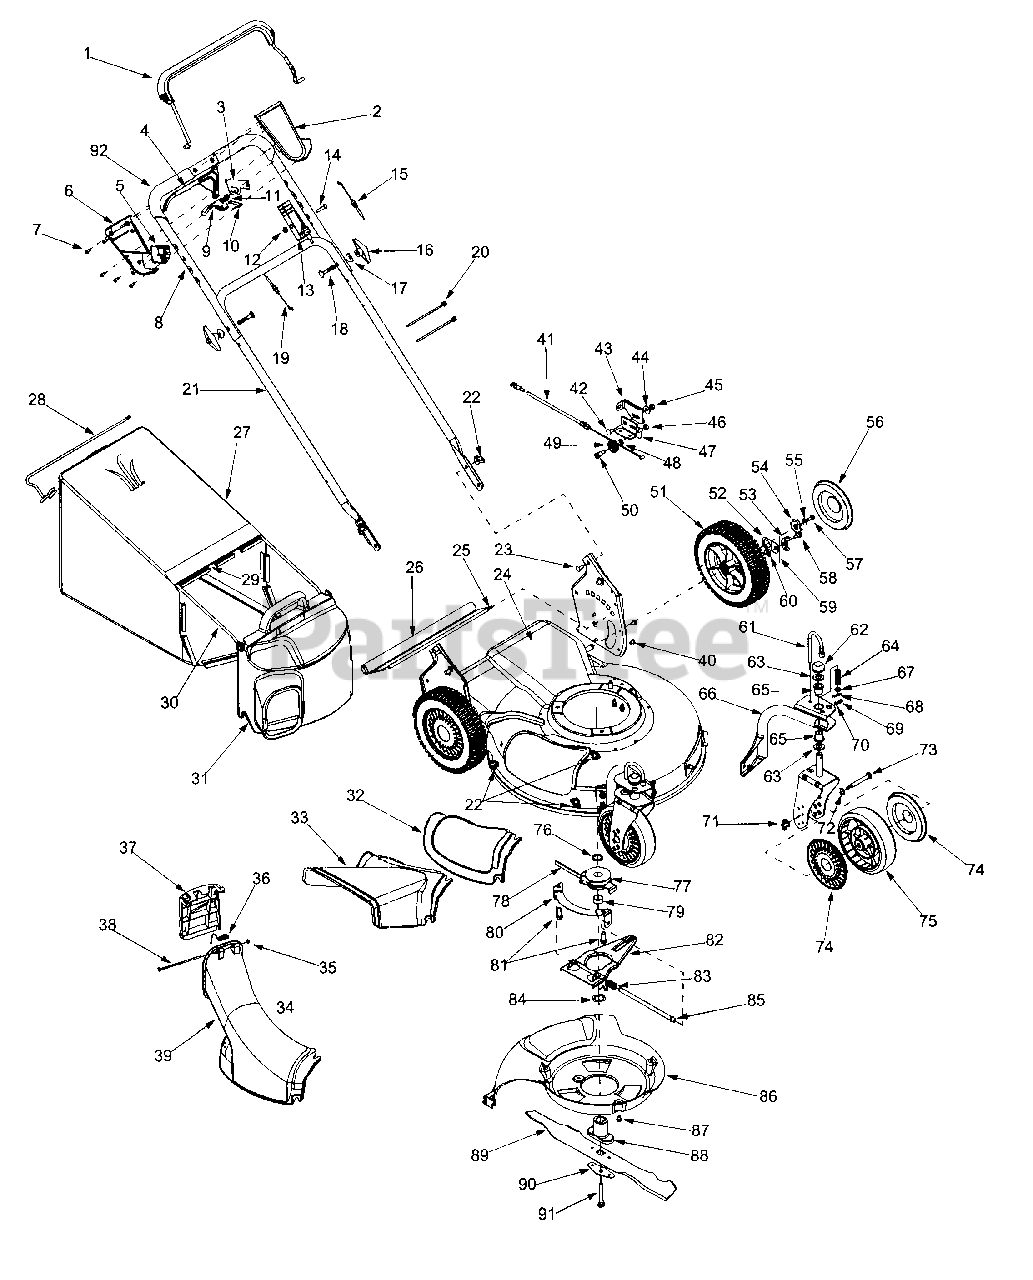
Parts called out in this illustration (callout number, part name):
1	Control Handle
2	Upper Control Handle
3	6 Spd. Rack Cable Bracket
4	Control Lever
5	Cable Mounting Cap
6	Lower Control Housing
7	C Sunk Tap Screw #10 x .75 Lg
9	6 Speed Shift Lever
10	Shift Lever Spring
11	Gear Insert
12	Top Lock Nut 1/4-20
13	Control Housing
14	Oval C-Sunk Screw
15	Control Cable 46"
16	Wing Nut
17	Saddle Washer .320 ID x .830 OD
18	Carriage Bolt 5/16-18 x 2.0
19	Drive Cable 51.0
20	Cable Tie
22	Wing Nut
23	Carriage Bolt 1/4-20 x .75
25	Trail Shield Wire
26	Trail Shield
27	Grassbag
31	Grassbag Cover
32	Mulch Cover
33	Side Discharge Chute
34	Chute Assembly
36	Torsion Spring
37	Chute Door
39	Discharge Chute
40	Screw 1/4-14 x .500
41	6 Speed Cable
42	Carriage Screw 1/4-20 x .50
45	Hex Nut 1/4-20
46	Hex Nut 1/4-28
49	Roller Cable
50	Shoulder Screw .375 ID x 1/4-14
51	Wheel 9 x 2
52	Ratchet Pawl Plate
54	Wheel Rachet
55	Bell Washer .265 ID x .75 OD
56	Rear Hubcap
57	Hex Cap Screw 1/4-20 x .620
58	Shld Screw .340 ID x .285 OD
59	Plastic Spring Ratchet
60	Top Lock Tab Weld Nut 1/4-20
63	Flat Washer 5/8" ID x 1.0" OD
64	Compression Spring
65	Flange Bearing
67	Flat Washer .330 ID x .830 OD
69	Grease Fitting
70	Flat Washer .203 ID x .403 OD
71	Wing Nut 1/4-20
73	Caster Axle .374 Dia x 2.50"
74	Front Hubcap
76	Sleeve Spacer .88 ID x 1.13 OD
77	Sleeve Spacer .88 ID x 1.13 OD
78	Belt 3/8 x 39.24
79	Sleeve Spacer .88 ID x 1.00 OD
81	Screw 3/8-18 x 1.0
84	Wave Washer 1.38 ID x .88 OD
86	Baffle
87	Screw 1/4-20 x 3.75
88	Blade Adapter Kit
89	21" Mulching Blade
90	Blade Bell Support
91	Hex Bolt 3/8-24 x 2.5
92	Grip
